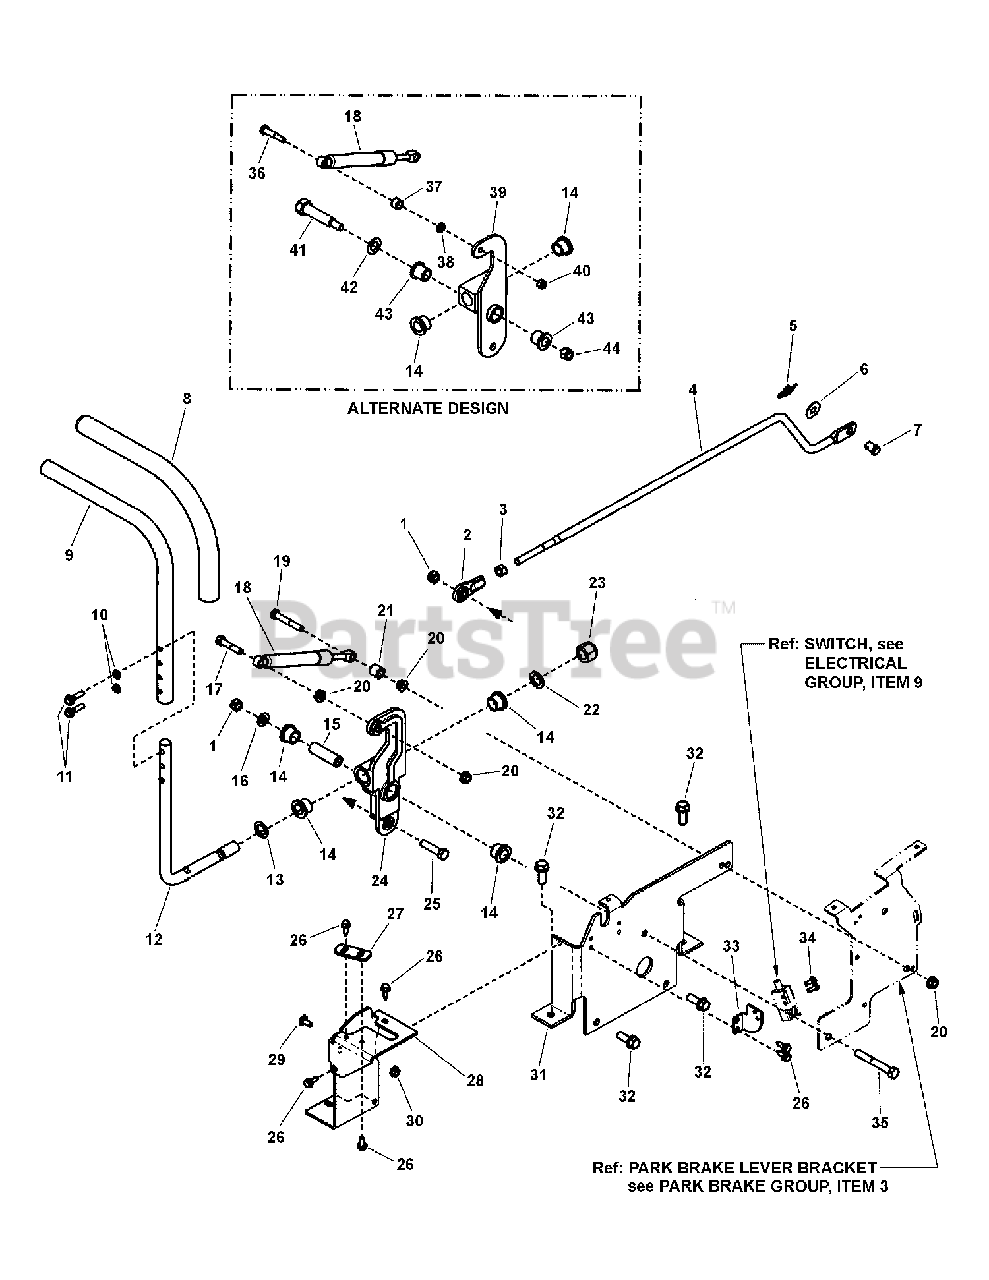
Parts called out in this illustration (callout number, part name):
1	NUT, 3/8-16 Hex Center Lock, YZ
2	ROD END, (3/8-24 thread)
3	NUT, 3/8-24 Hex, GR B, YZ
4	ROD, Link Foward/Reverse (3/8-24 thread)
5	COTTER PIN, 1/2 Self, YZ
6	WASHER, 7/16" Flat
7	PIN, 7/16 x 1" Clevis
8	GRIP, Handle
9	HANDLE
10	LOCKWASHER, 1/4" Spring, YZ
11	SCREW, 1/4-20 x 1" Hex Head Cap, GR 5, BZ
12	ROD, Handle
13	WASHER, .64 x .99 x .05 Flat, YZ
14	BUSHING, Bronze, 5/8 x 5/8
15	SPACER, Sleeve, RZT
16	WASHER, 3/8" Flat (SAE)
17	SCREW, 5/16-18 x 1-1/2 Hex Head Cap, YZ
18	DAMPENER, Control
19	SCREW, 5/16-18 x 2" Hex Head Cap, GR 5, YZ
20	NUT, 5/16-18 Hex Flange Lock, GR 5, YZ
21	SPACER, .625 OD x .380 ID x .564 L
22	WASHER, 5/8 ID x 1.00 OD x .065 Nylon
23	NUT, 5/8-18 Hex Nyloc, YZ
24	ARM, Die Cast Aluminum
25	SCREW, 3/8-16 x 1-1/2 Hex Head Cap, GR 5, YZ
26	SCREW, 1/4-20 x 3/4" Hex Washer Self-Tap, Black
27	PLATE, Foward/Reverse Adjust
28	BRACKET, Guide, Stick, Control, LH
29	BOLT, 1/4-20 x 5/8" Round Head Short Square Neck, GR 5, YZ
30	NUT, 1/4-20 Hex Flange Lock, Black
31	CONTROL BRACKET, LH
32	SCREW, 3/8-16 x 1" Hex Washer Self-Tap
33	BRACKET, Switch
34	SCREW, #10-24 x 1/2" Hex Washer Self-Tap, Torx
35	SCREW, 3/8-16 x 3-1/4" Hex Head Cap, GR 5
36	SHOULDER BOLT, 1/4-20 x .313 Dia.
37	SPACER, .33 x .50 x .355, Yellow
38	WASHER, 1/4" Flat, Hardened
39	WELDMENT, Control Bracket, LH - Black
40	NUT, 1/4-20 Hex Nyloc, YZ
41	SHOULDER BOLT, 3/8-16
42	WASHER, Thrust .562 x 1.000 x .031
43	BEARING, Flange, 9/16
44	NUT, 3/8-16 Hex Nyloc, YZ
